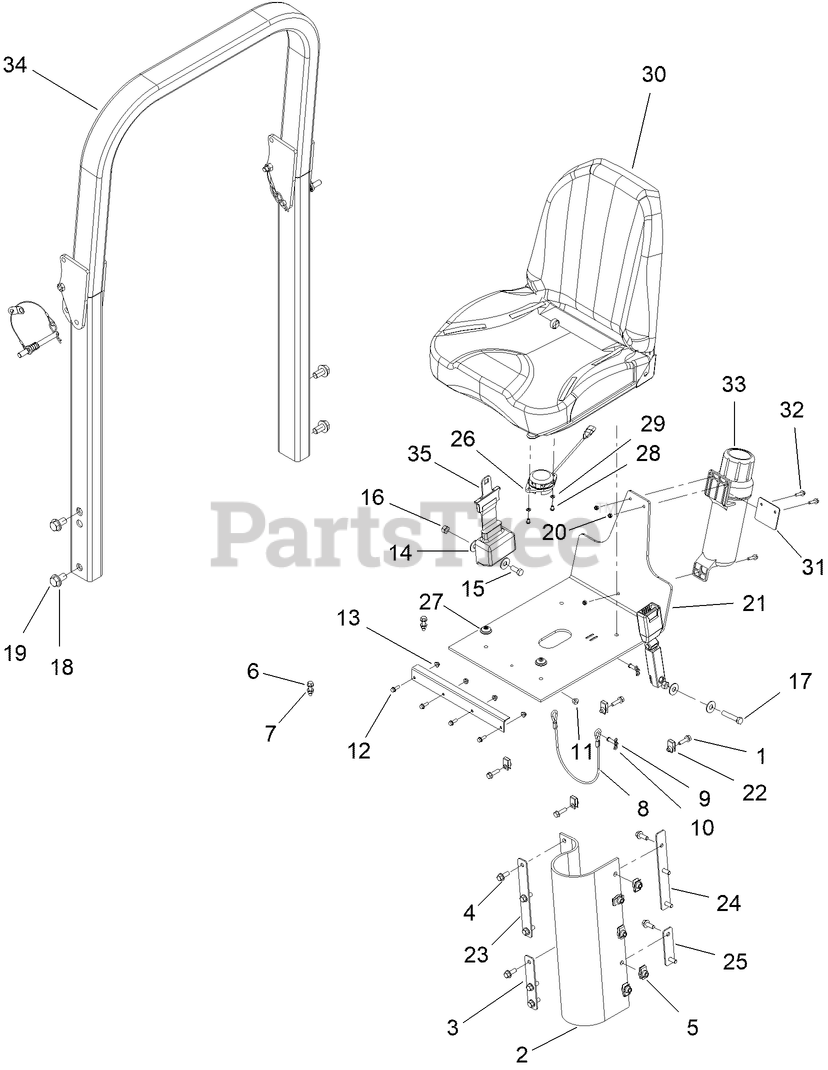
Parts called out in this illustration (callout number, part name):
1	SCREW-HHF
2	SHIELD-RUBBER
4	SCREW-HHF
5	NUT-TINNERMAN
6	SCREW-HHF
7	NUT-HF, NI
8	CABLE-SEAT
9	PIN-CLEVIS
10	PIN-COTTER, LOCKING
11	NUT-HF
12	SCREW-HHF
13	NUT-HF
14	WASHER-FLAT
15	SCREW-HH
16	NUT-HEX
17	SCREW-HH
18	WASHER-FLAT
19	SCREW-HH
20	NUT-HEX, NI
21	SEAT BASE-WELDED
26	SEAT SWITCH
27	CUP-WASHER
28	SCREW-HSBH
29	WASHER-PLAIN
30	SEAT - LOW PROFILE GRAY
31	PLATE-MANUAL TUBE SUPPORT
32	SCREW-HHF M6 X 25
33	MANUAL COMPARTMENT
34	ROPS-FOLDING
35	SEAT BELT ASM
